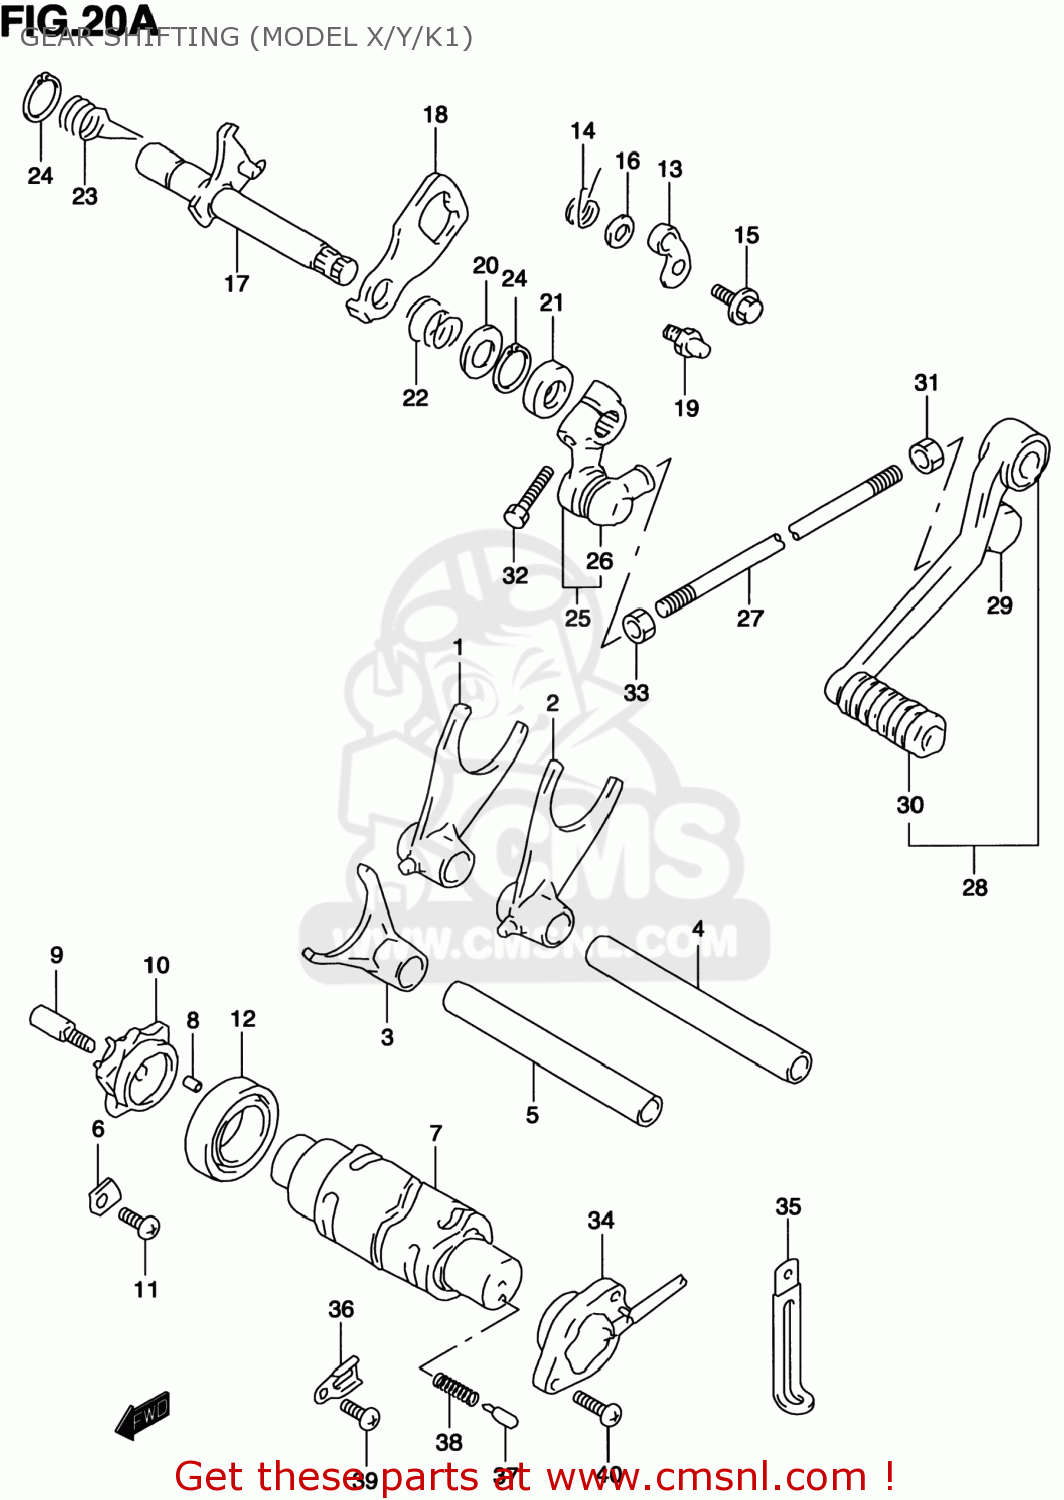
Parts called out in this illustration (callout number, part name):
1	FORK,GEAR SHIFT
2	FORK,GEAR SHIFT NO.1
3	FORK,GEAR SHIFT NO.3
4	SHAFT,GEAR SHIFT FORK
5	SHAFT,GEAR SHIFT FORK NO.2
6	RETAINER
7	CAM,GEAR SHIFT
8	PIN
9	PIN,SHIFT CAM DRIVEN GEAR
10	PLATE,GEAR SHIFT CAM
11	SCREW
12	BEARING
13	STOPPER,GEAR SHIFT CAM
14	SPRING,SHIFT CAM STOPPER
15	BOLT(6X14.3)
16	WASHER
17	SHAFT,GEAR SHIFT
18	PLATE,GEAR SHIFT CAM DRIVE
19	STOPPER,GEAR SHIFT CAM
20	SHIM(14X22X1)
21	SEAL,OIL(14X22X6)
22	SPRING
23	SPRING
24	CIRCLIP
25	ARM,GEAR SHIFT LINK
26	COVER,DUST
27	ROD,GEAR SHIFT LINK
28	LEVER ASSY,GEAR SHIFT
29	COVER,DUST
30	RUBBER,GEAR SHIFT PEDAL
31	NUT
32	BOLT
33	NUT
34	BASE ASSY,GEAR SHIFT TERMINAL
35	CLAMP(L:65)
36	CLAMP,GENERATOR LEAD WIRE
37	PIN(5X15.5)
38	SPRING
39	SCREW
40	SCREW
